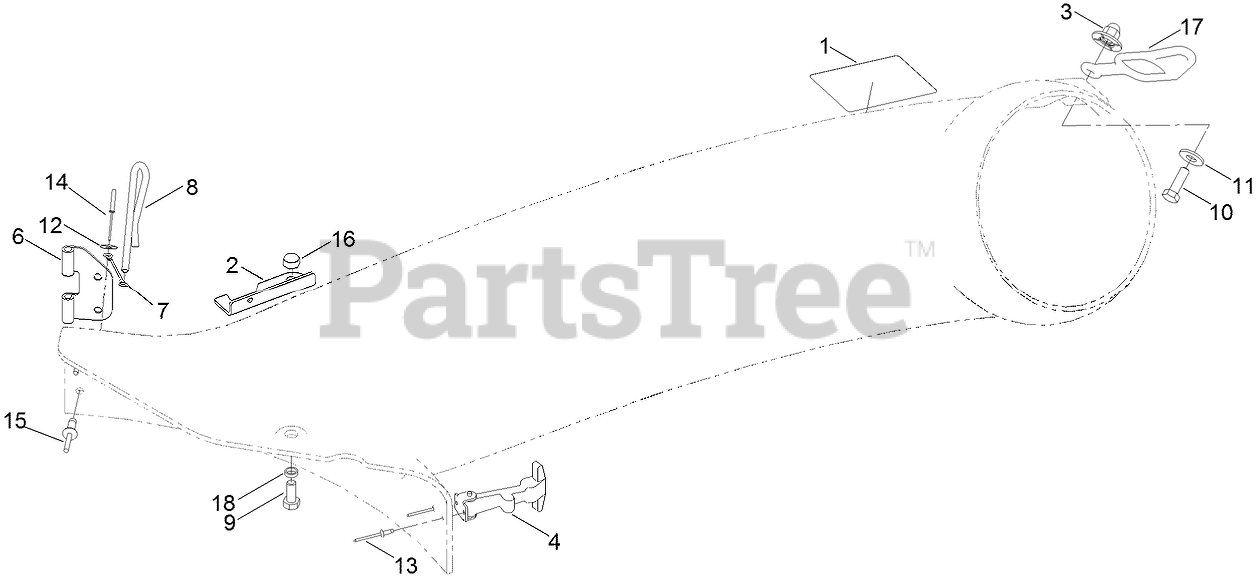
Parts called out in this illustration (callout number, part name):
1	DECAL-DANGER
3	NUT-IMPELLER
4	HANDLE ASM
6	BRACKET-CHUTE MOUNTING
7	LANYARD
8	PIN-LOCKING, CHUTE
9	SCREW-HH
10	SCREW-HH
11	WASHER-FLAT
12	WASHER-PLAIN
13	RIVET-POP
14	RIVET-BLIND
15	RIVET-BLIND
16	NUT-HEX
17	RETAINER-DUCT
18	BUSHING
